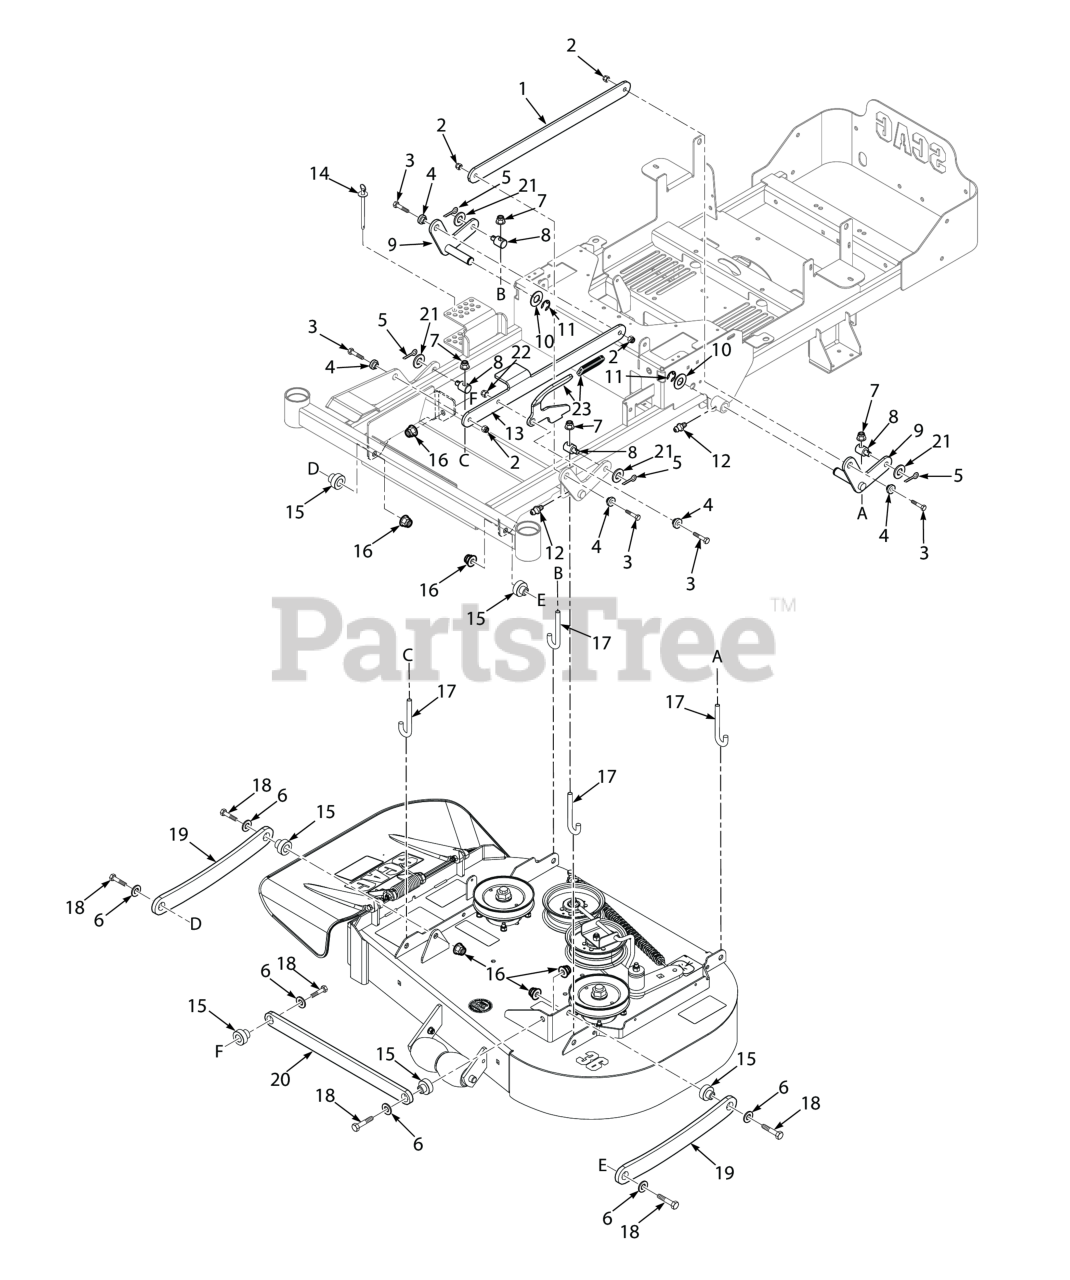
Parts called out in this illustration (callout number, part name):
1	Link, Deck Lift - LH
2	Nut, Flange Elastic Stop Nut, 3/8-16
3	Bolt, Hex Head 3/8-16 x 1-1/4", Kawasaki FX / FT & FT-EFI
4	BUSHING, SPEED ADJUSTMENT LEVER
5	Pin, Cotter 3/16 x 1.0"
6	Flatwasher, 1/2 - .531 x 1.062 x .095
7	HEX LOCKNUT, ELASTIC STOP, 1/2-13
8	Joint, Swivel
9	Lift Bellcrank Weldment
10	Flatwasher, 3/4 (.766 x 1.250 x .060)
11	RETAINING RING, 3/4" EXTERNAL "E"
12	GREASE FITTING, STR. 1/4-28 SELF TAP.
13	Link, Deck Lift - RH
14	Pin Assembly, Deck Height
15	Bushing, Deck Lift
16	Nut, Elastic Stop 1/2-13, (STT-52 & STTII-52)
17	Rod, Deck Lift
18	Bolt, Hex Head 1/2-13 x 1-3/4"
19	Pull Arm, Deck
20	Lateral Link
21	Flatwasher, 5/8" (.656 x 1.312 x .095")
22	HEX NUT, ELASTIC STOP LOCK, 3/8-16
23	Lever Assembly (incl. Grip)
